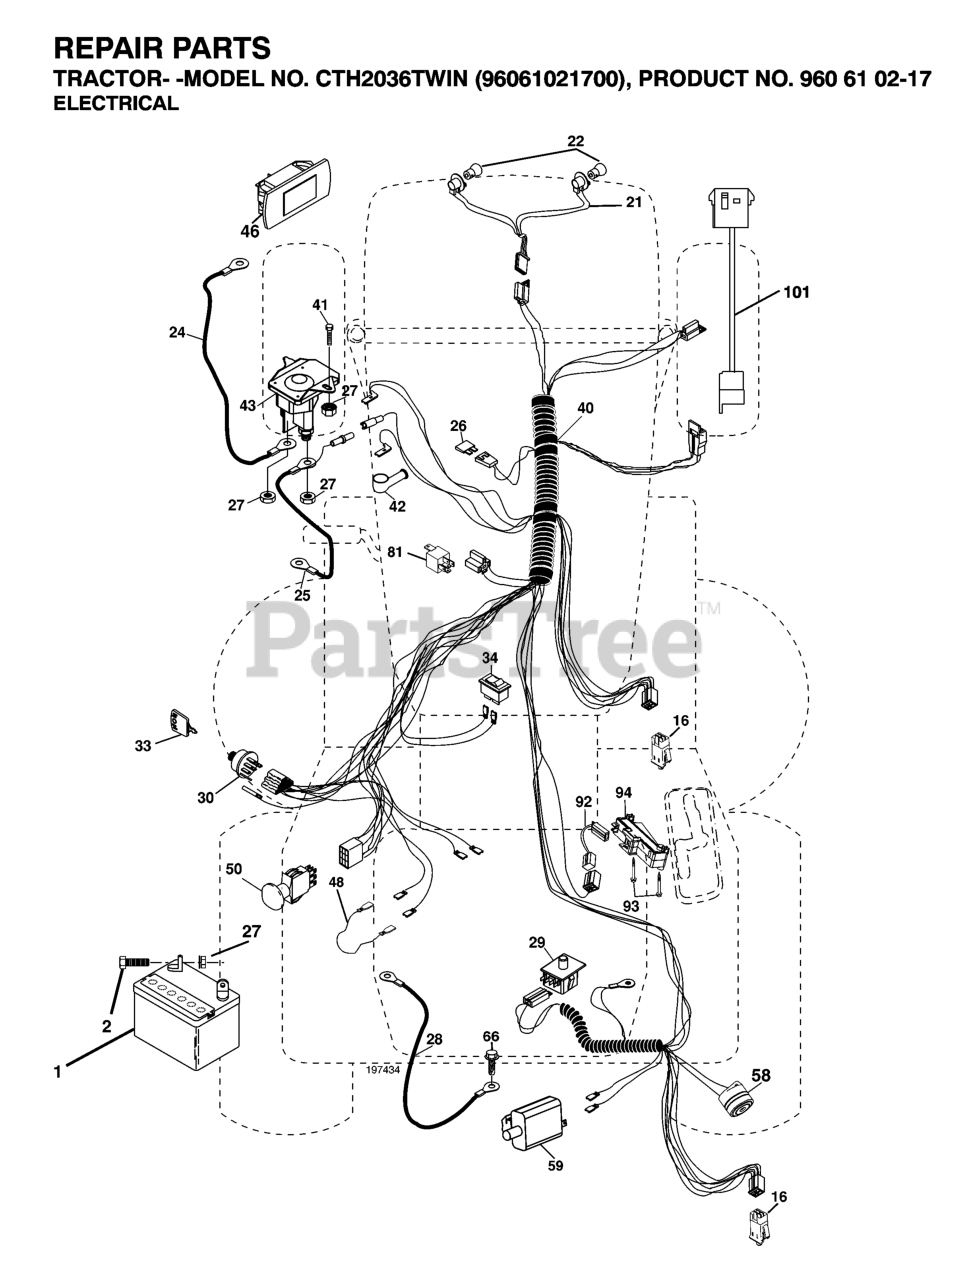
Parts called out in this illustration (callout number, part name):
1	BATTERY 12V .35 AMP
2	BOLT.HEX.1/4.X.3/4.DICHROMATE
16	SWITCH INTERLOOK PUSH-IN
21	HARNESS ASSY LIGHT
24	CABLE.BATTERY.6GA.16"RED
25	CABLE BATTERY
26	FUSE 20AMP
27	NUT
28	CABLE GROUND
29	SWITCH.SEAT.DP W/RAMPS
30	SWITCH.IGN.DELTA.W.LGH.ROS
33	KEY MLD GEN DELTA
40	RP HARNESS.IGN.ELECT.REG.CRD
41	BOLT
42	TERMINAL COVER
43	SOLENOID.W/BRASS.PLUNGER
46	RP.GUAGE.SRVCMNDR.HRMTR.
48	ADAPTER.AMMETER
50	RP.PTO.SWITCH.8 TERMINAL.BLACK
58	BUZZER
59	.WITCH.FULL BAGGER.INDICATOR
81	RELAY.ASSY.T
92	HARNESS.PIGTAIL.CONSLE
93	SCREW.PLASTITE
94	MODULE.REVERSE.ROS
